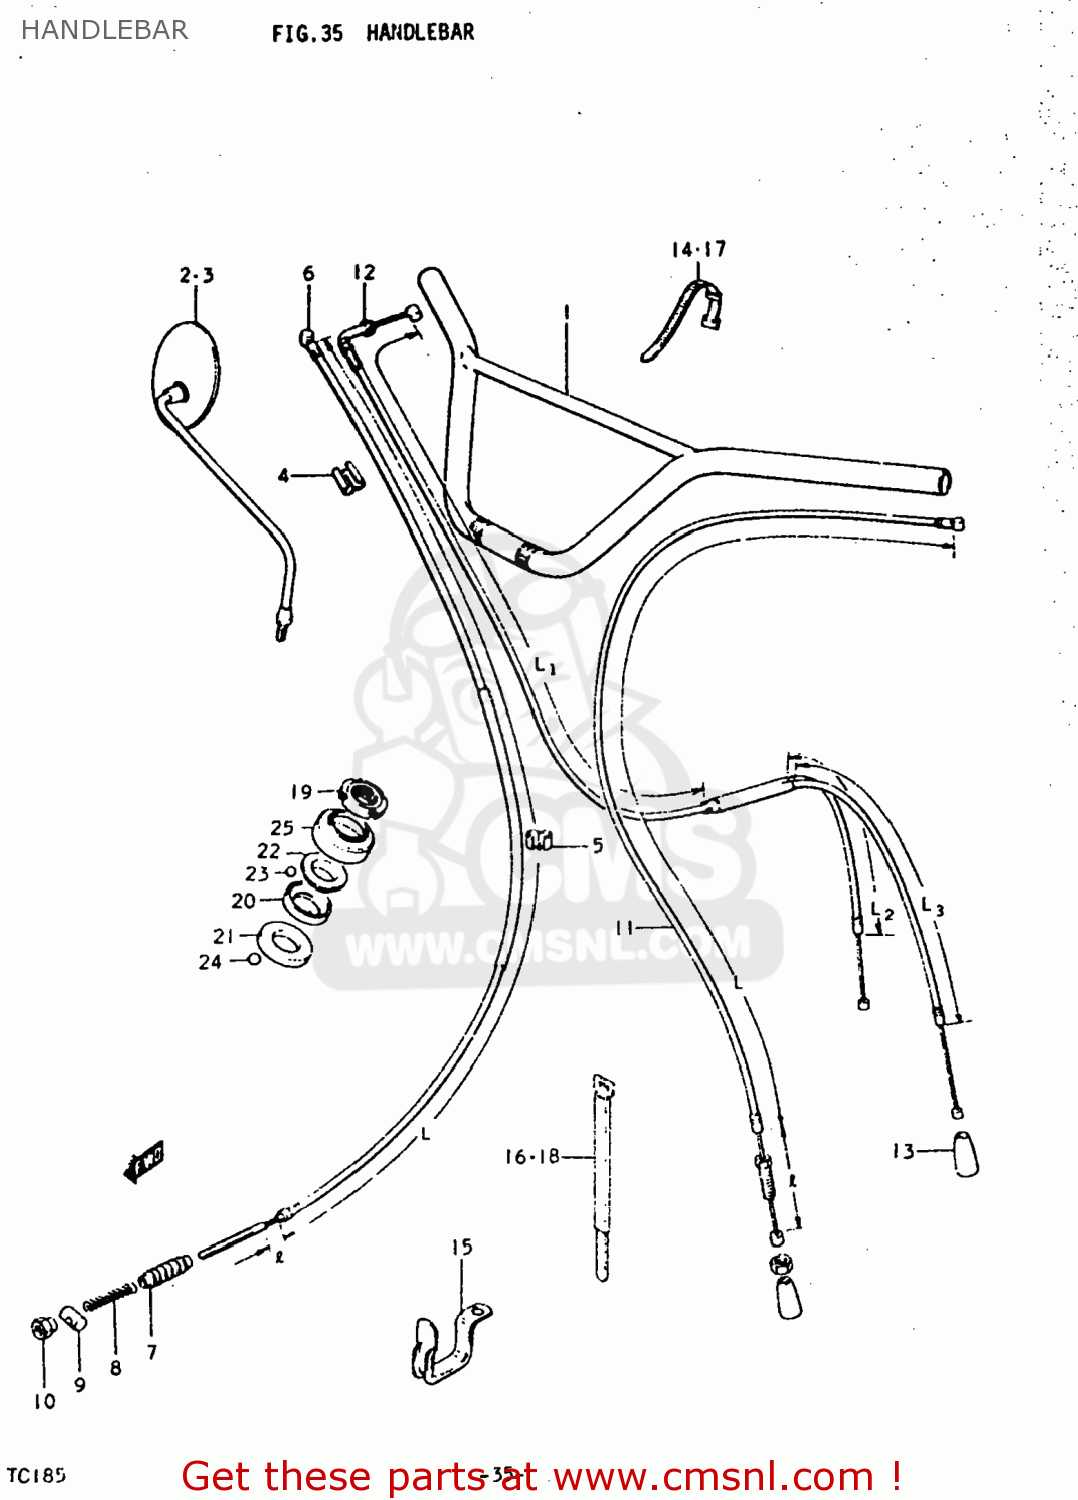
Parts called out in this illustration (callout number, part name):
1	HANDLEBAR
2	MIRROR ASSEMBLY,RIGHT
3	MIRROR ASSEMBLY,LEFT
4	CLIP
5	CLIP
6	CABLE ASSEMBLY,FRONT BRAKE
7	SEAL,DUST(7X16X75)
8	SPRING
9	PIN,10X19
10	NUT
11	CABLE ASSY,CLUTCH
12	CABLE ASSEMBLY,THROTTLE
13	SEAL,DUST(7X18X30)
14	CLAMP(L:120)
15	CLAMP
16	CLAMP
17	CLAMP(L:120)
18	CLAMP
19	NUT,STEERING STEM(25X44X10)
20	RACE,STEERING INNER UPR
21	LACE,STEERING INNER LWR
22	RACE,STEERING OUTER UPR
23	BALL
24	BALL
25	DUST SEAL,STEERING UPR
